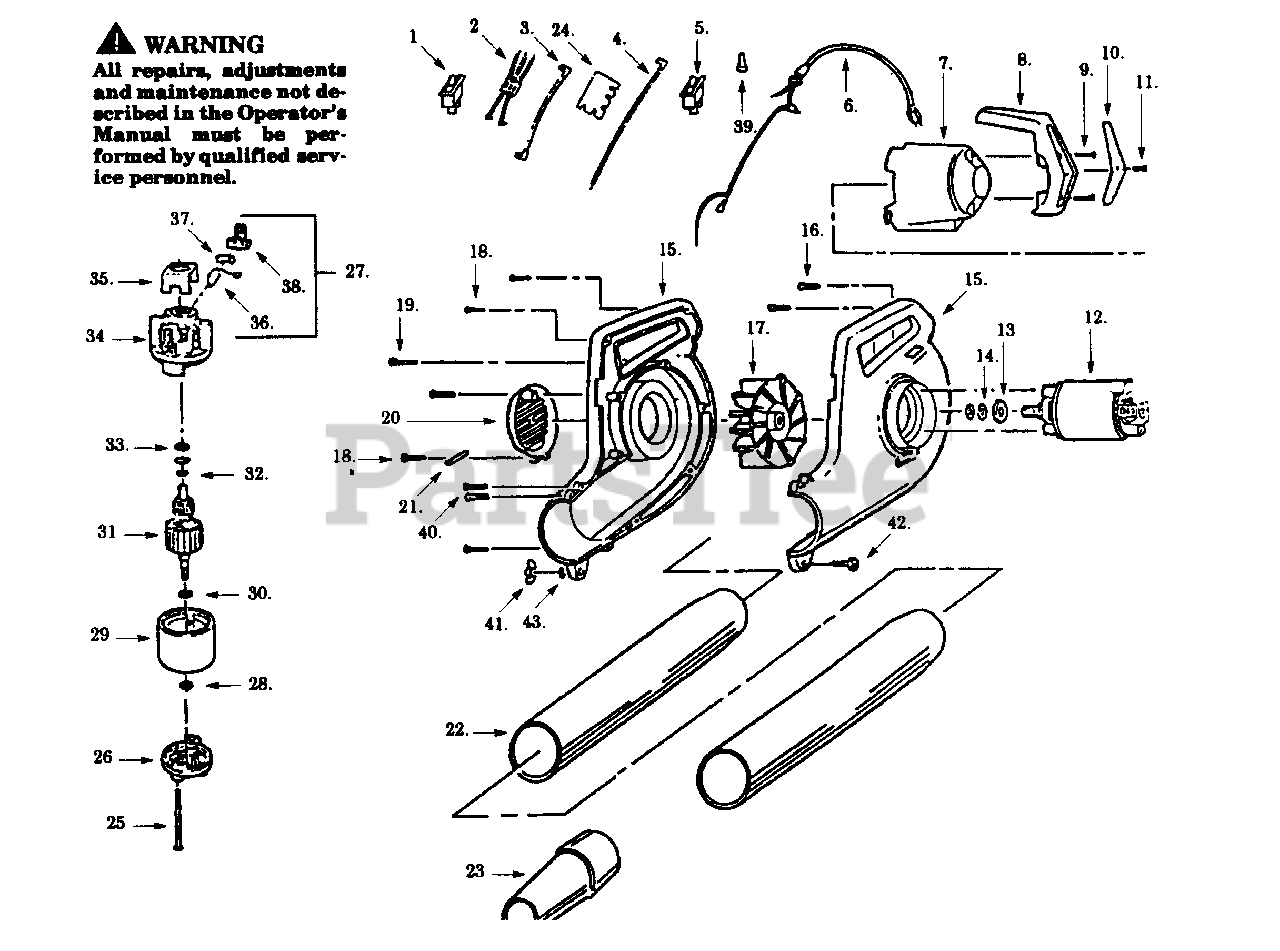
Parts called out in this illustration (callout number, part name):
1	On-Off Switch
2	P.C. Board Ass'y.
3	Lead Wire Ass'y.
4	Lead Wire Ass'y.
5	Speed Switch
6	Power Cord Ass'y.
7	Motor Cover
14	Retaining Ring
15	L.H./R.H. Housing
17	Impeller
20	Inlet Cover
21	Hinge Pin
22	Outlet Tube
24	Mounting Board
26	Endbell (Output)
27	Brush Kit (Inc. 36,37,38)
29	Field Assembly
30	Retainer Ring
31	Armature
32	Retainer Ring
34	Endbell (Brush)
35	Insulator
37	Brush Spring
38	Brush Holder
39	Connector
41	Wing Nut
